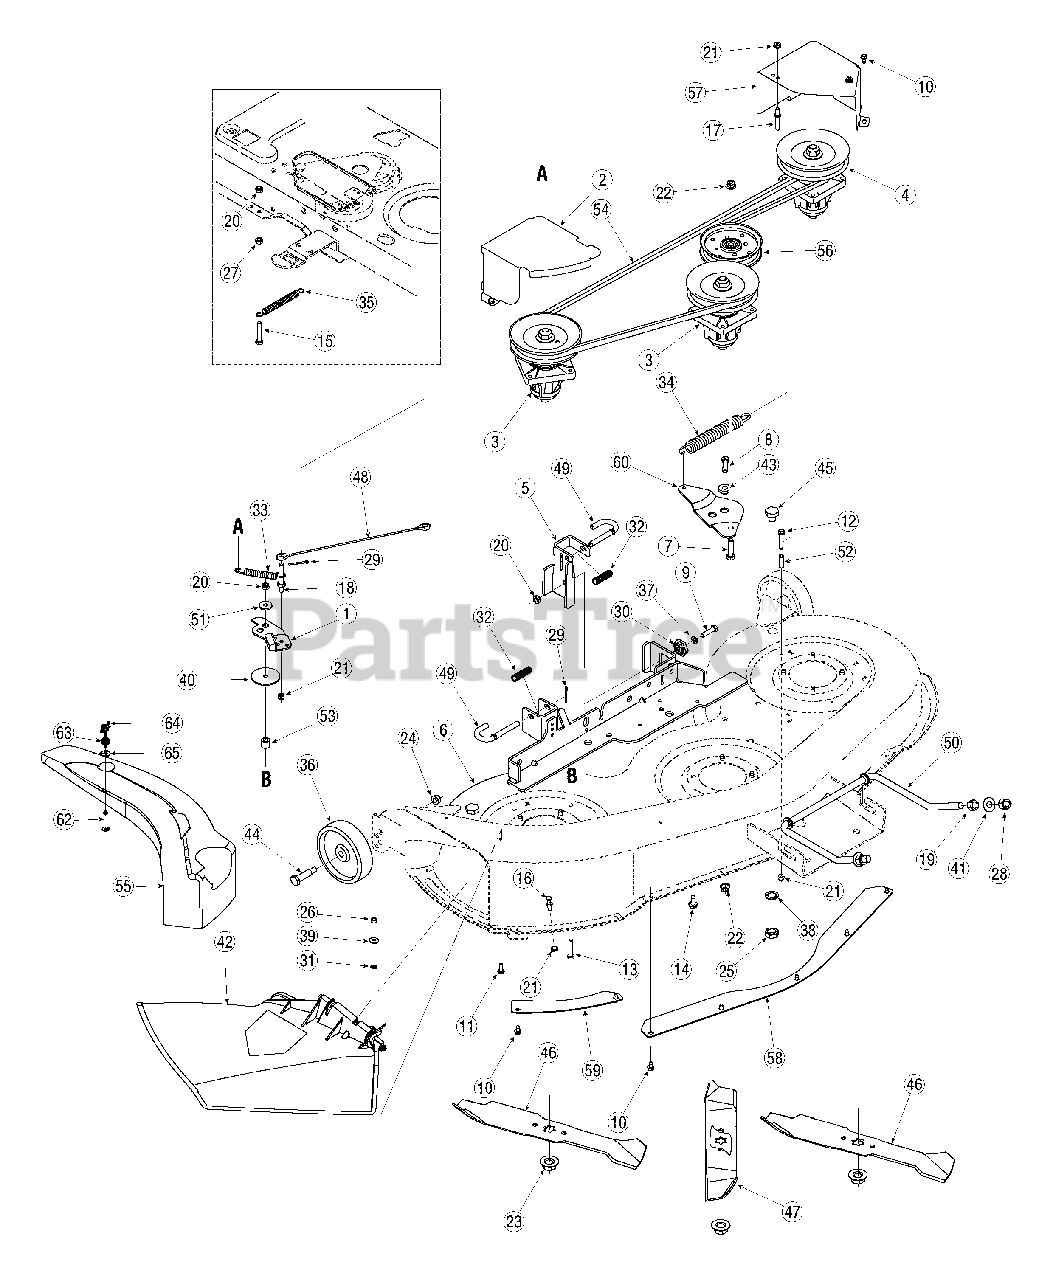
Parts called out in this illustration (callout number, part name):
1	Brake Assembly, Deck
3	Spindle Assembly, 5.00 Dia.
4	Spindle Ass'y, Double Pulley
7	Screw, 3/8-16, 1.50, Gr5
8	Screw, 3/8-16, 1.00, Gr5
9	Screw, 5/16-18, 1.25, Gr5
10	Screw, 1/4-20, 0.500
11	Screw, 1/4-20 x.75, Gr5
12	Screw, 1/4-20, 1.500
13	Screw, 5/16-18, 1.50, Gr5
14	Screw, Ld, 5/16-18, 0.750
15	Screw, 5/16-18, 1.75, Gr5
16	Pin, Grass catcher, 1/4-20
17	Belt Guard Pin 1/4 Dia x 1.43
18	Pin, 1/4-20, 3/8 x 2.0
19	Nut, Hex, 1/2-13, Gr5
20	Nut, Flange Lock, 5/16-18, Gr F, Nylon
21	Nut, Flange Lock, 1/4-20, Gr F, Nylon
22	Nut, Flange Lock, 3/8-16, Gr F, Nylon
23	Nut, Flange, 5/8-18
24	Nut, Flange Lock, 3/8-16, Gr F
25	Nut, Hex, M16-1.5
26	Nut, Hex, 1/4-20, Gr5
27	Nut, Hex, 5/16-18, Gr5
28	Nut, Hex Lock, 1/2-13, Gr8, Nylon
29	Pin, Cot, 1/8 x 1.25
30	Adjustment Gear, Deck
31	Nut, Push,.25 ID x.50 OD
32	Spring, Compression,.531 OD x 1.75
33	Spring, Extension,.50 Dia x 3.97
34	Spring, Extension,.91 Dia x 7.33
35	Spring, Extension,.68 OD x 5.00 Lg
36	Wheel, Deck 5.0 x 1.38
37	Washer, Lock, 5/16
38	Washer, Lock, 5/8
39	Washer, Bell,.265 x.75 x.062
40	Washer, Flat,.34 x 2.25 x.10
41	Washer, Flat,.51 x 1.12 x.06
42	Chute Assembly
43	Spacer, Shoulder,.625 ID x.169
44	Spacer, Shoulder,.498 x 1.53, 3/8-16
45	Plug, Screw, M16 x 1.5
46	Blade, 16.28", Star 3-in-One
47	Blade, 14.88", Star 3-in-One
48	Cable, 12.00"
49	Rod, Deck Release
50	Rod, Deck
51	Shoulder Spacer
52	Spacer,.260 x.372 x 1.030
53	Spacer,.375 x.63 x.595
54	Belt, V-Type, Poly
55	Mulch Plug
56	Pulley, Idler, 4.25" Dia.
62	Screw, 1/4-20 x 1.500
63	Hex Nut, 1/4-20
64	Wing Nut, 1/4-20
65	Flat Washer,.28 x.74 x.063
